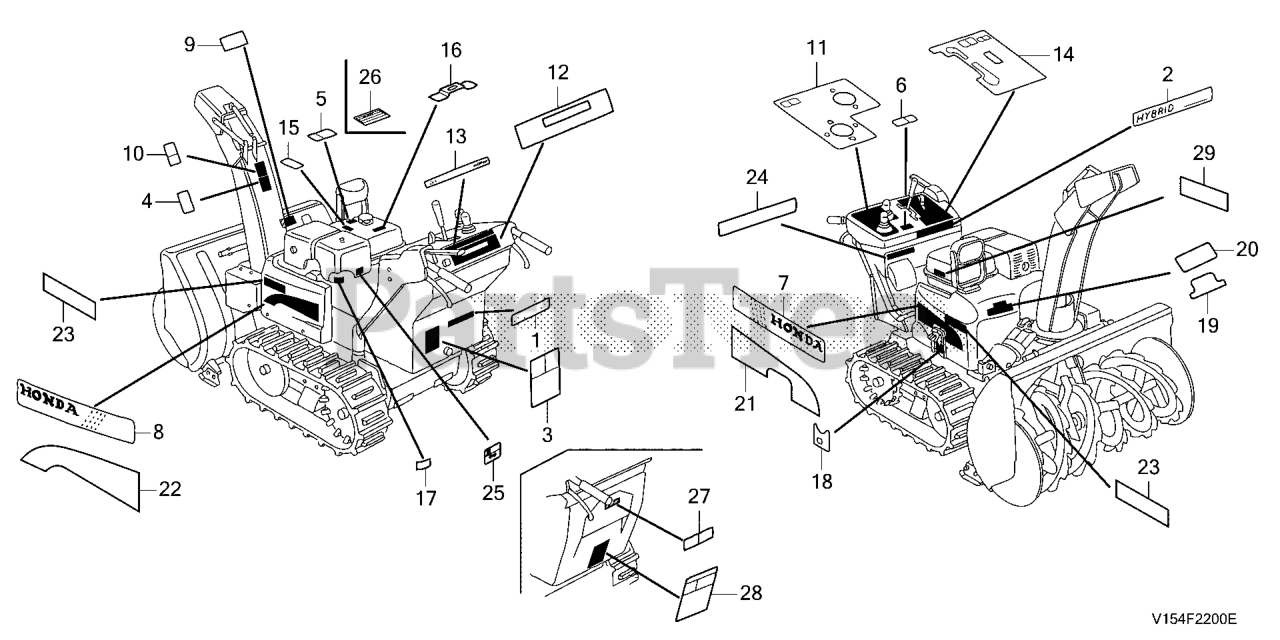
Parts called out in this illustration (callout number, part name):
4	LABEL, WARNING (ENGLISH)
9	MARK, HOUSING DANGER (ENGLISH)
10	MARK, DISCHARGE DANGER (ENGLISH)
11	MARK, CONTROL OPERATION
12	MARK, ENGINE SWITCH (ENGLISH)
14	MARK, THROTTLE (ENGLISH)
18	MARK, OIL CAUTION
20	MARK, EMBLEM (HSM1336I)
21	MARK, R. STRIPE
22	MARK, L. STRIPE
23	MARK A, HONDA
24	MARK B, HONDA
25	MARK, FUEL INDICATION (ENGLISH)
27	LABEL, BATTERY PRODUCT DANGER
28	LABEL, WARNING (ENGLISH)
29	LABEL, WARNING
